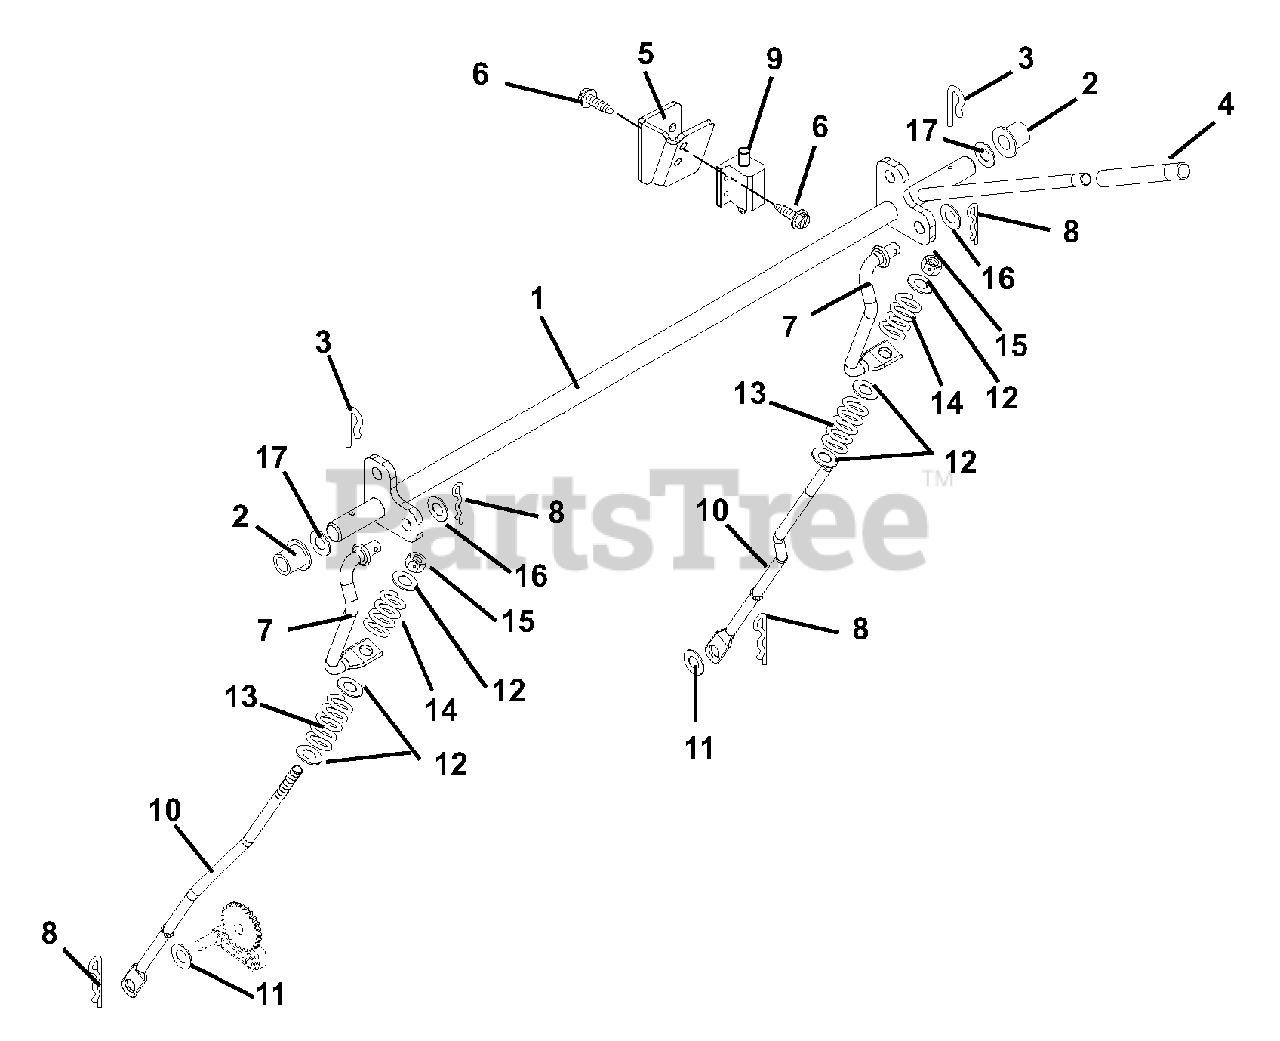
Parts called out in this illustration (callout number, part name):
1	WMT, ZOOM BRAKE ROD
2	BSHG-FLG .630X1.000X.625 NY
3	PIN, SPRING CLIP
4	GRIP,HAND CLUTCH LEVER
5	BRACKET, BRAKE SWITCH
6	@SCR-TAP 10-24X.50 HWH TR YWZC
7	ROD-OVER CENTER
8	PIN-HAIR, ENDRIES #25 YWZC
9	SWITCH,INTERLOCK
10	ROD-PARK BRAKE EZT
11	WSHR-FL-STL .406X1.00X.188 YWZ
12	@WSHR-FL-STL.344X.688X.065YWZC
13	SG-COMP .045X.50X1.187
14	SG-COMP .063X.53X1.187
15	@NUT-LK-NYL .312-18 YWZC
16	@WSHR-FL-STL.406X.812X.065 YWZ
17	WSHR-FL-STL .627X.990X.032
